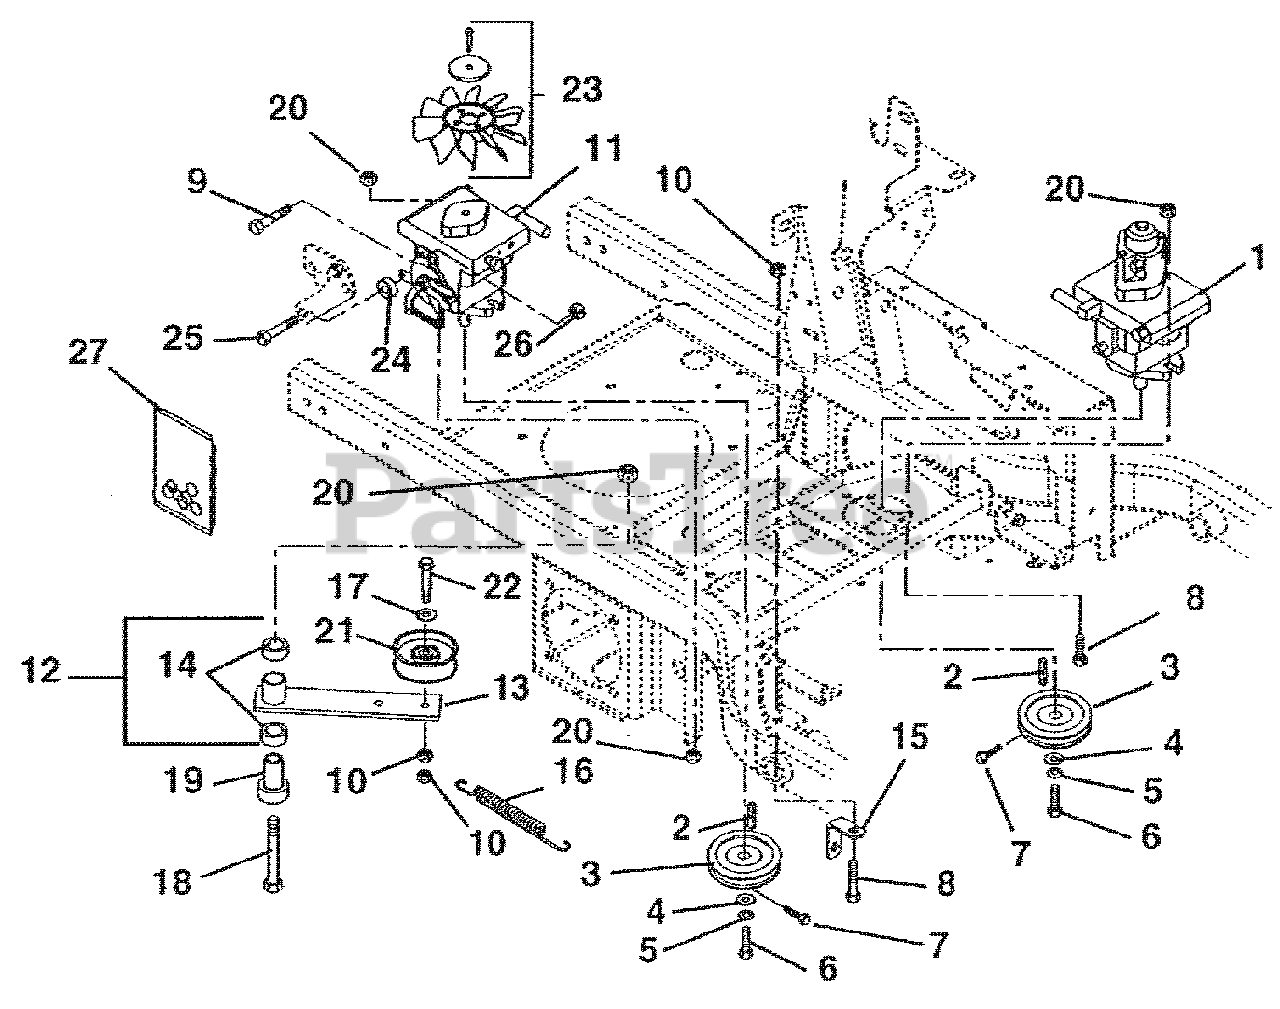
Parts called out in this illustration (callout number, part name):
1	Pump, Hydraulic BDP-21 with Auxiliary
2	Key, Square 5x 5030mm Plain
3	Sheave, Poly V .671 x 4.125
4	Washer, Flat Steel .281 x 1.00 x .063
5	Washer, Locking .25 x .062
6	Bolt, Hex M6 x 1.0 x 12
7	Screw, Socket Head .25-20 x .50
8	Bolt, Hex .50-13 x 1.50 Grade 5
9	Bolt, Hex .31-18 x .75 Grade 5
10	Nut-Locking-Top-Flange .38-16
11	Pump, Hydraulic BDP-21 with Thru Fan
12	Assembly, Idler Arm Guard Drive (includes 13 &14)
13	Weldment, Idler Arm Ground Drive
14	Bearing, 1.00 x 1.12 x .75
15	Anchor, Spring Idler
16	Spring, Tension .120 x .845 x 6.500
17	Washer, Flat Steel .39 x.75 x .125
18	Bolt, Hex .50-13 x 3.50 Grade 5
19	Bearing, Pedestal Powered Metal
20	Nut, Locking Top Flange .50-13
21	Idler, Flat 4.00 x 1.06
22	Bolt, Hex .38-16 x 2.75 Grade 5
23	Fan, Hydro Pump Cooling
24	Spacer .318 x .43 x .375
25	Bolt, Hex .31-18 x 1.25 Grade 5
26	Nut, Locking Top Flange .31-18
27	Kit, Pump Seal (BDP-10A)(One kit required for each pump)
